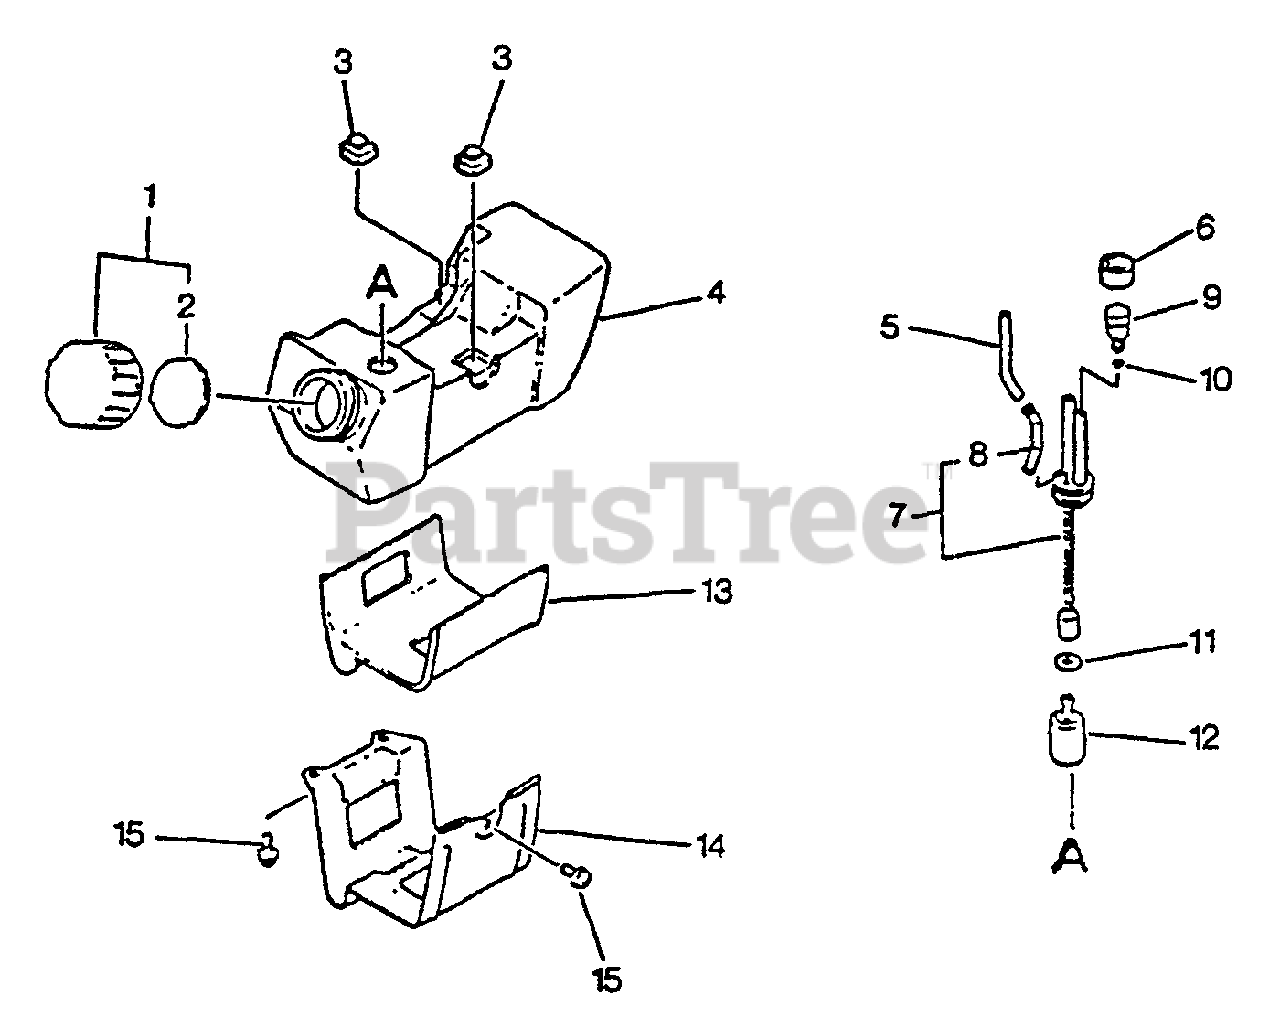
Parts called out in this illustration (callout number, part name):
1	CAP ASSY
2	GASKET, FUEL CAP
3	CUSHION
4	TANK, FUEL
5	PIPE, FUEL 3×6×45
6	HOLDER, VENT
7	PIPE, FUEL
8	CONNECTOR, PIPE
9	VENT ASSY
11	WASHER 5.5×12×0.8
12	FILTER, FUEL
13	CUSHION
14	GUARD, FUEL TANK
15	SCREW 5×10
